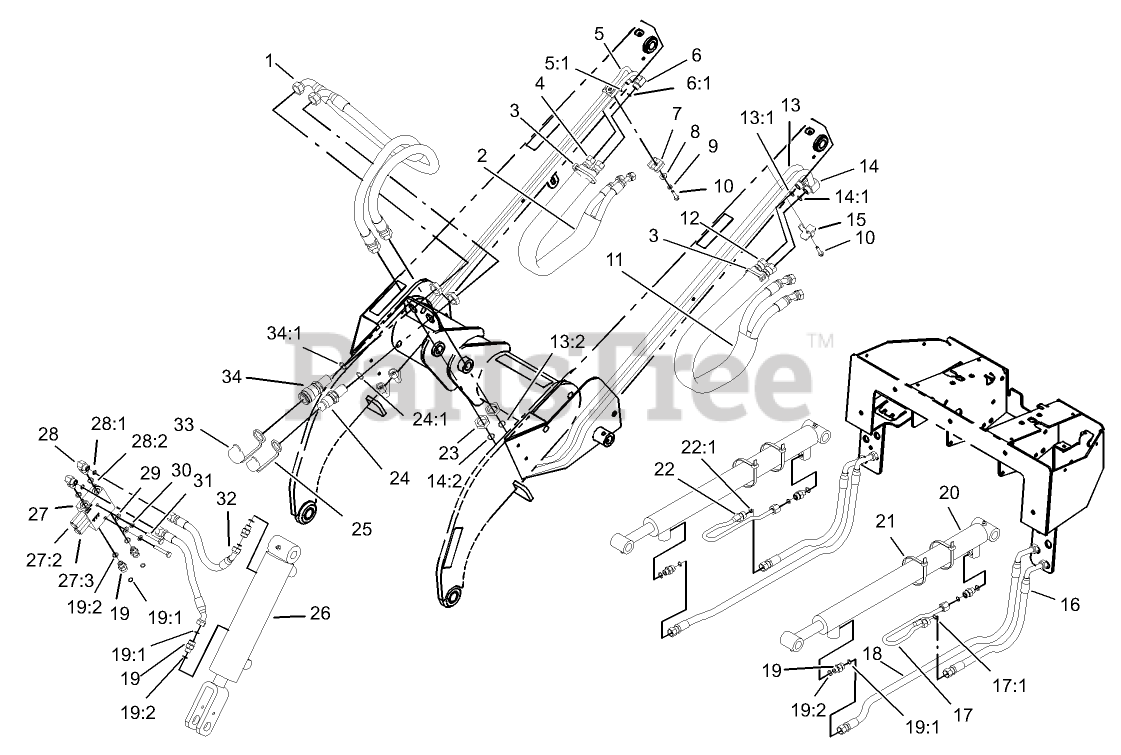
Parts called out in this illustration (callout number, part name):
1	HOSE ASM
2	SLEEVE-PROTECTIVE
3	TIE-CABLE
4	HOSE-HYD
5	HYD TUBE ASM
5:1	O-RING
6	HYD TUBE ASM
6:1	O-RING
7	CLAMP-TUBE
8	WASHER-FLAT
9	WASHER-LOCK
10	SCREW-HWH
11	SLEEVE-PROTECTIVE
12	HOSE-HYD
13	HYD TUBE ASM
13:1	O-RING
13:2	O-RING
14	HYD TUBE ASM
14:1	O-RING
14:2	O-RING
15	PLATE-CLAMP, TUBE
16	HOSE-HYD
17	HYD TUBE ASM
17:1	O-RING
18	HYD HOSE ASM
19	FITTING-STRAIGHT
19:1	O-RING
19:2	O-RING
20	CYLINDER-LIFT
21	TIE-CABLE
22	HYD TUBE ASM
22:1	O-RING
23	NUT-LOCK, BULKHEAD
24	BULKHEAD NIPPLE ASM
24:1	O-RING
25	CAP-DUST, NIPPLE
26	CYLINDER-TILT
27	VALVE-RELIEF, CROSSOVER
27:2	CARTRIDGE-RELIEF
27:3	CARTRIDGE-RELIEF
28	FITTING-ELBOW, 90 DEG
28:1	O-RING
28:2	O-RING
29	WASHER-PLAIN
30	WASHER-LOCK
31	SCREW-HH
32	HOSE-HYD
33	CAP-DUST, COUPLER
34	BULKHEAD COUPLER ASM
34:1	O-RING
